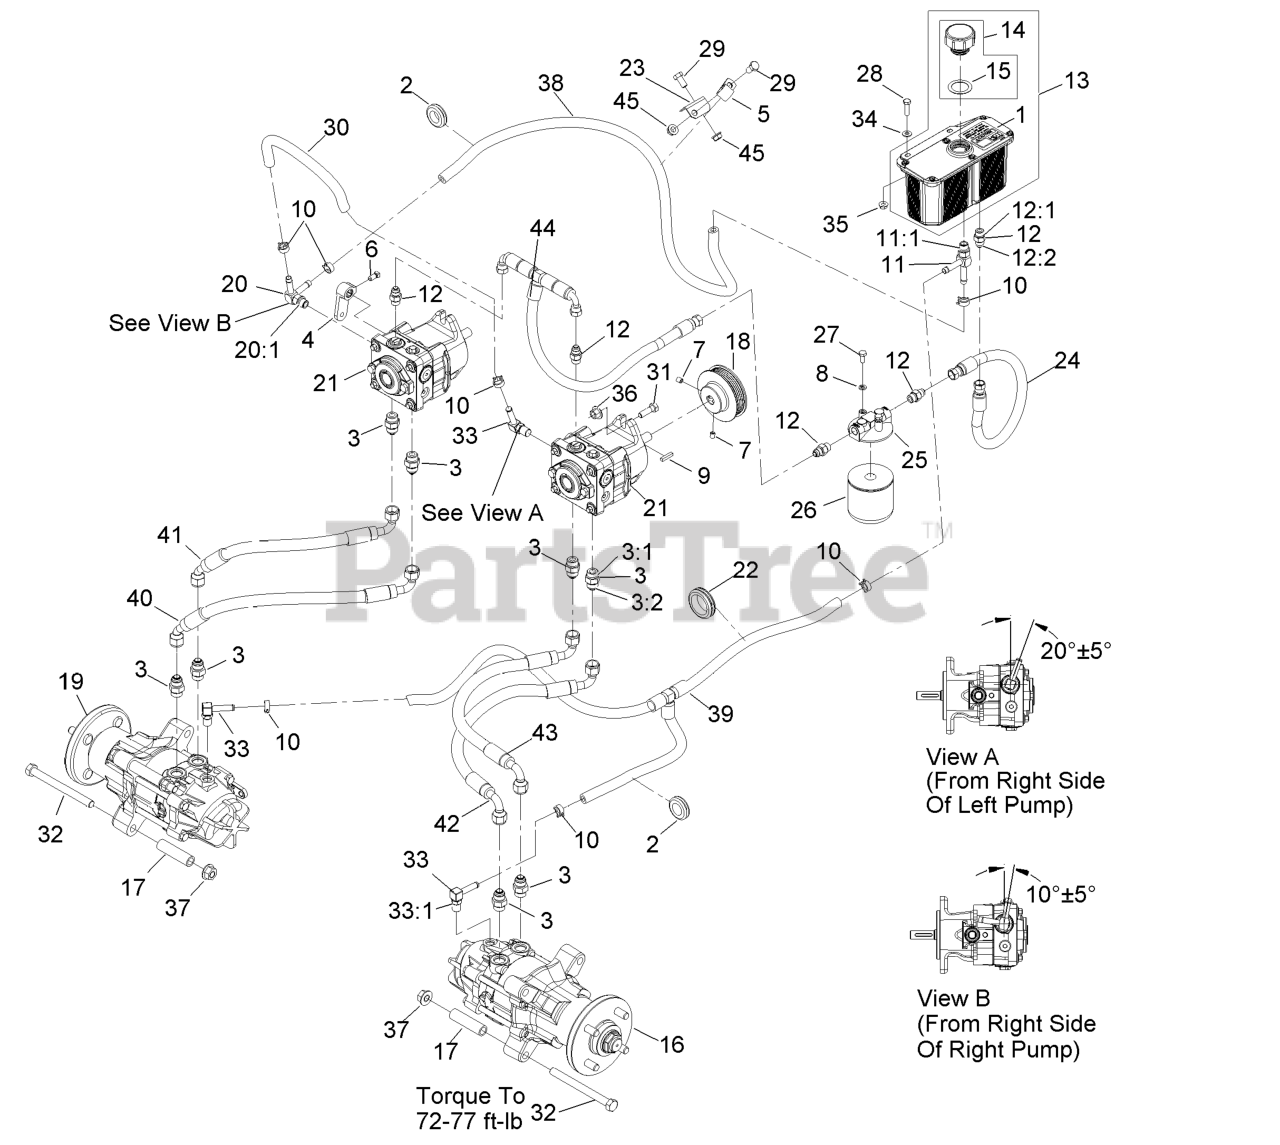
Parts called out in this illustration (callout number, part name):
1	DECAL-HYDRAULIC TANK
2	GROMMET
3	FITTING-STRAIGHT
4	ARM-CONTROL, PUMP
5	CLIP-LOOM
6	SCREW-SET
7	SCREW-SET
8	WASHER-LOCK
10	CLAMP-HOSE
11	ADAPTER-RUN, TEE
11:1	O-RING
12	FITTING-STRAIGHT
12:1	O-RING
13	HYD RESERVOIR ASM
14	KIT,HYD RES CAP W/GASKET
15	GASKET-CAP
16	MOTOR,PRM18-LH
16:5	ASM, WHEEL HUB W/STUDS
19	MOTOR,PRM18-RH
20	ADAPTER-TEE
20:1	O-RING
22	GROMMET
23	BRACKET-CLAMP
24	HYDRAULIC HOSE ASM
25	HEAD-FILTER
26	FILTER-25 MICRON, BI-DIRE
26	ELEMENT-FILTER, WINTER
27	SCREW-HH
28	SCREW-HH
29	SCREW-HH
30	HOSE-HYD
31	SCREW-HH
32	SCREW-HH
33	FITTING-ELBOW, 90
34	WASHER-FLAT
36	NUT-FLANGE
37	NUT-HHF
38	HOSE-HYD
39	ASM,HYDRAULIC HOSE
40	ASM,HYDRAULIC HOSE
41	ASM,HYDRAULIC HOSE
42	ASM,HYDRAULIC HOSE
43	ASM,HYDRAULIC HOSE
44	HYDRAULIC HOSE ASM
45	NUT-HHF, WHIZ
